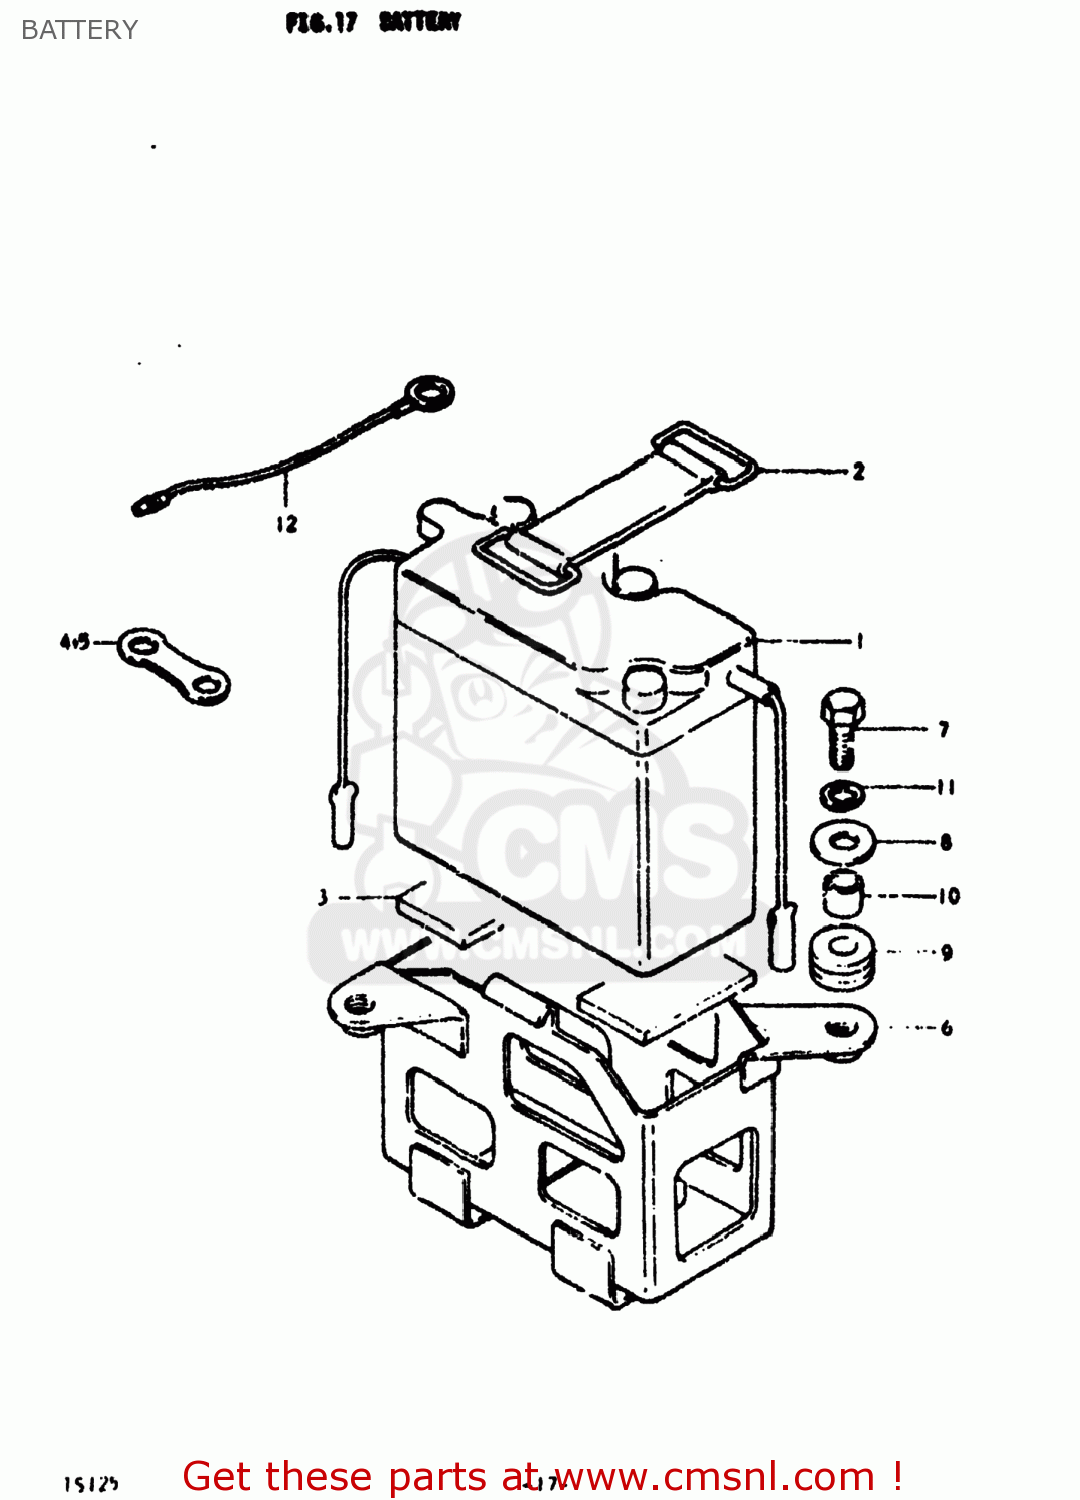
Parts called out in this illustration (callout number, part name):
1	BATTERY(6N4B-2A,6V4.2AH)
2	BAND
3	CUSHION 20X45X6
4	CLAMP
5	CLAMP
6	HOLDER,BATTERY
7	BOLT
8	WASHER (6.5X20X1.2)
9	CUSHION
10	SPACER (7X9X7)
11	LOCK WASHER
12	LEAD WIRE
